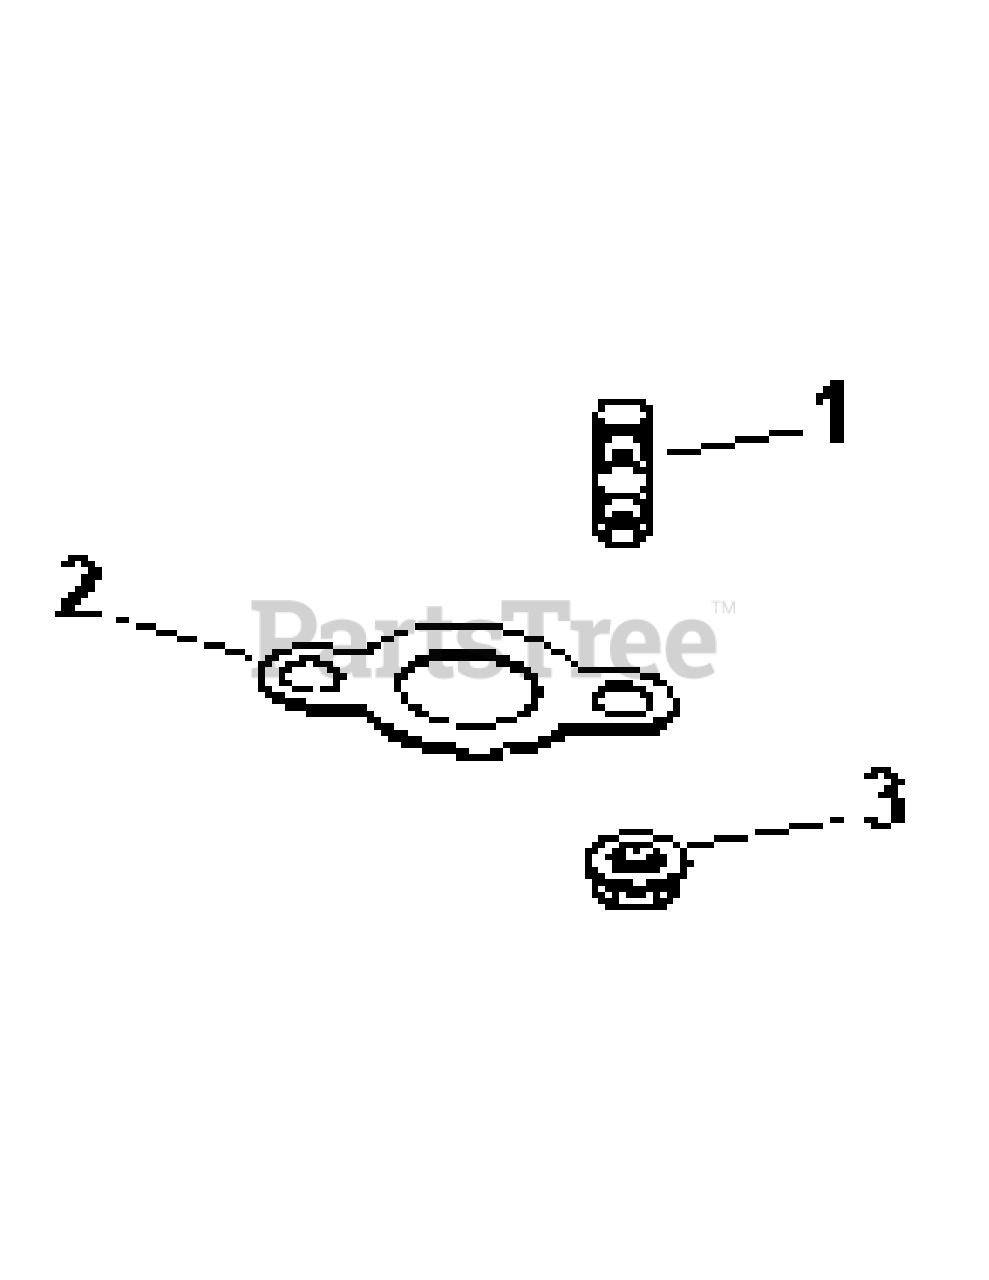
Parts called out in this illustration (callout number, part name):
1	Stud (M8 x 1.25 x 33)
2	Exhaust Gasket
3	Muffler Mounting Nut (M8 x 1.25)
